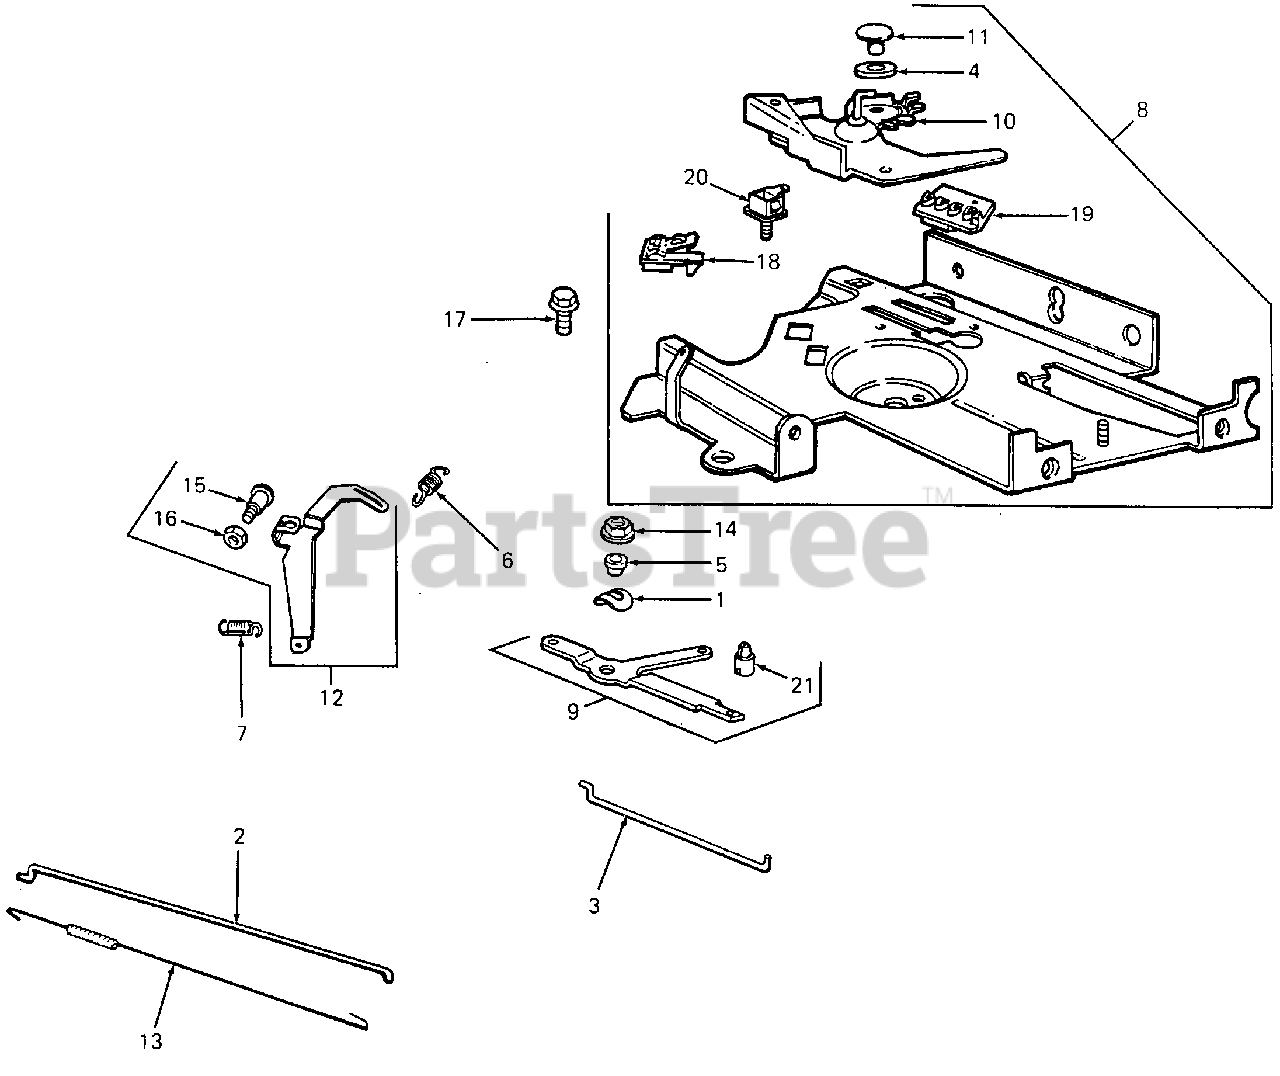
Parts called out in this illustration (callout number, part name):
1	Washer, Spring
2	Link, Governor
3	Link, Governor Control
4	Bushing, Lever
5	Bushing, Lever
6	Spring, Governor
7	Spring, Idler
8	Plate, Governor
9	Lever, Governor
10	Lever & Rivet Assy
12	Lever Assy
13	Spring, Governor Link
17	Screw, Mtg
18	Switch, Stop
19	Gear, Rack
20	Insulator Assy
21	Retainer, Link
